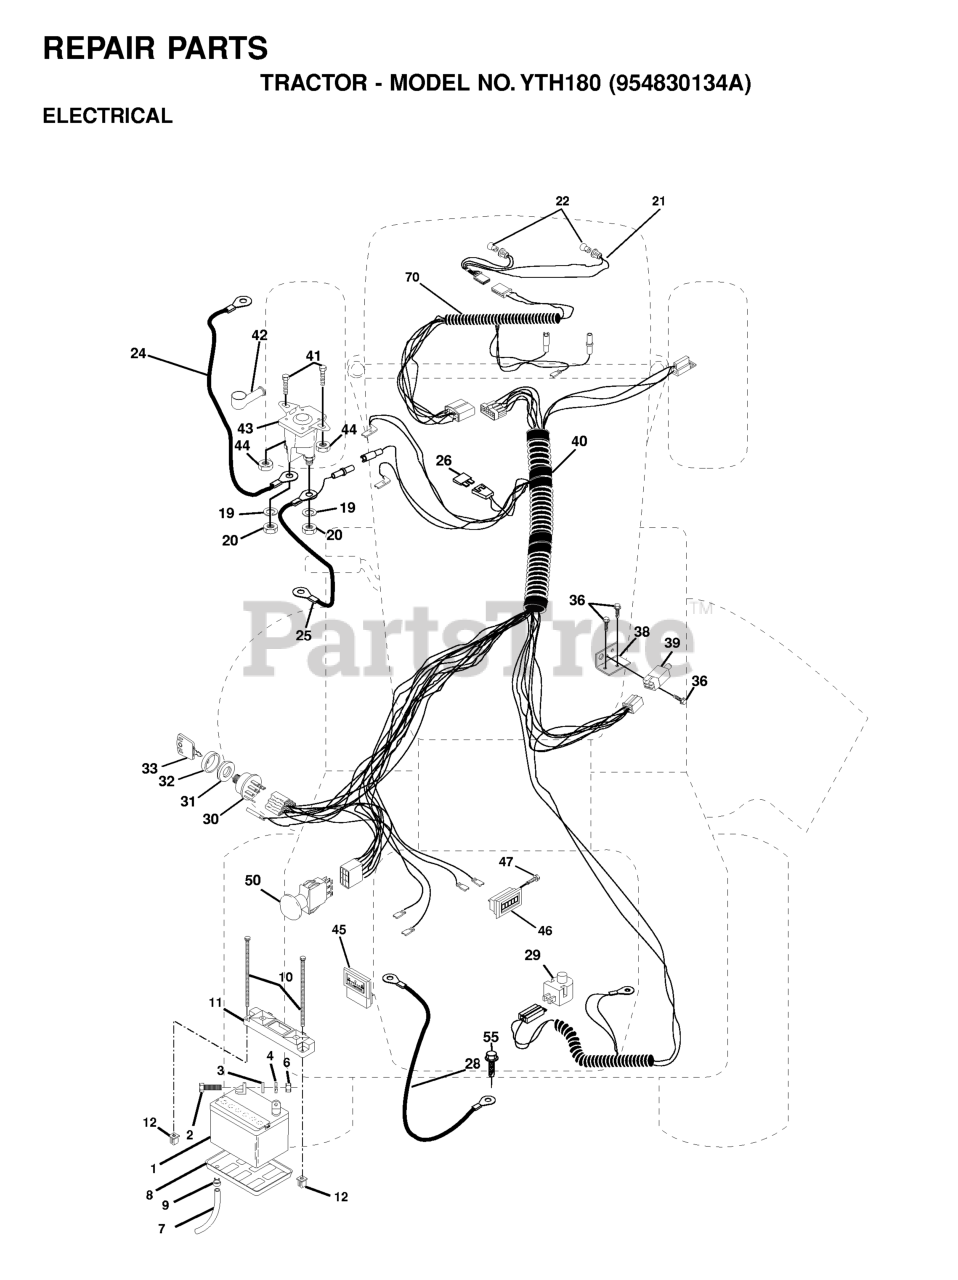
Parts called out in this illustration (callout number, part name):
1	BATTERY
2	BOLT.HEX.1/4.X.3/4.DICHROMATE
4	LOCKWASHER
6	NUT
7	PLASTIC TUBE
8	BATTERY TRAY T
9	HOSE CLAMP T
10	BOLT 1/4-20 X 7.5
11	HOLDDOWN, BATTERY, DASH MOUNT
12	NUT, PUSH NYLON 1/4" BATTERY
19	LOCKWASHER
20	NUT
21	HARNESS ASM HDLIG
24	BATTERY CABLE GT
25	CABLE BATTERY 6 GA 22" W/16W
28	CABLE GROUND 6 GA 21" 90T BLK
29	RP.SWITCH.PLUNGER.NC.GRAY
30	SWITCH.IGNITION.4.POSITION
31	NUT IGNITION
32	COVER SWITCH KEY
33	KEY.MOLDED.GENERIC
38	SWITCH BRACKET
39	SWITCH INTERLOCKT
40	HARNESS IGN ELEC P/L
41	BOLT
42	TERMINAL COVER
43	SOLINOID
44	Nut, Keps Blk Hex 1/4-20 UNC
46	HOUR METER T
47	Screw 10-24 x 1/2 Black
50	SWITCH-PTO
55	Screw 5/16-18 x 1/2 Hex, Self Tapping 5/16-18 x 1/2
70	HARNESS, ENGINE
